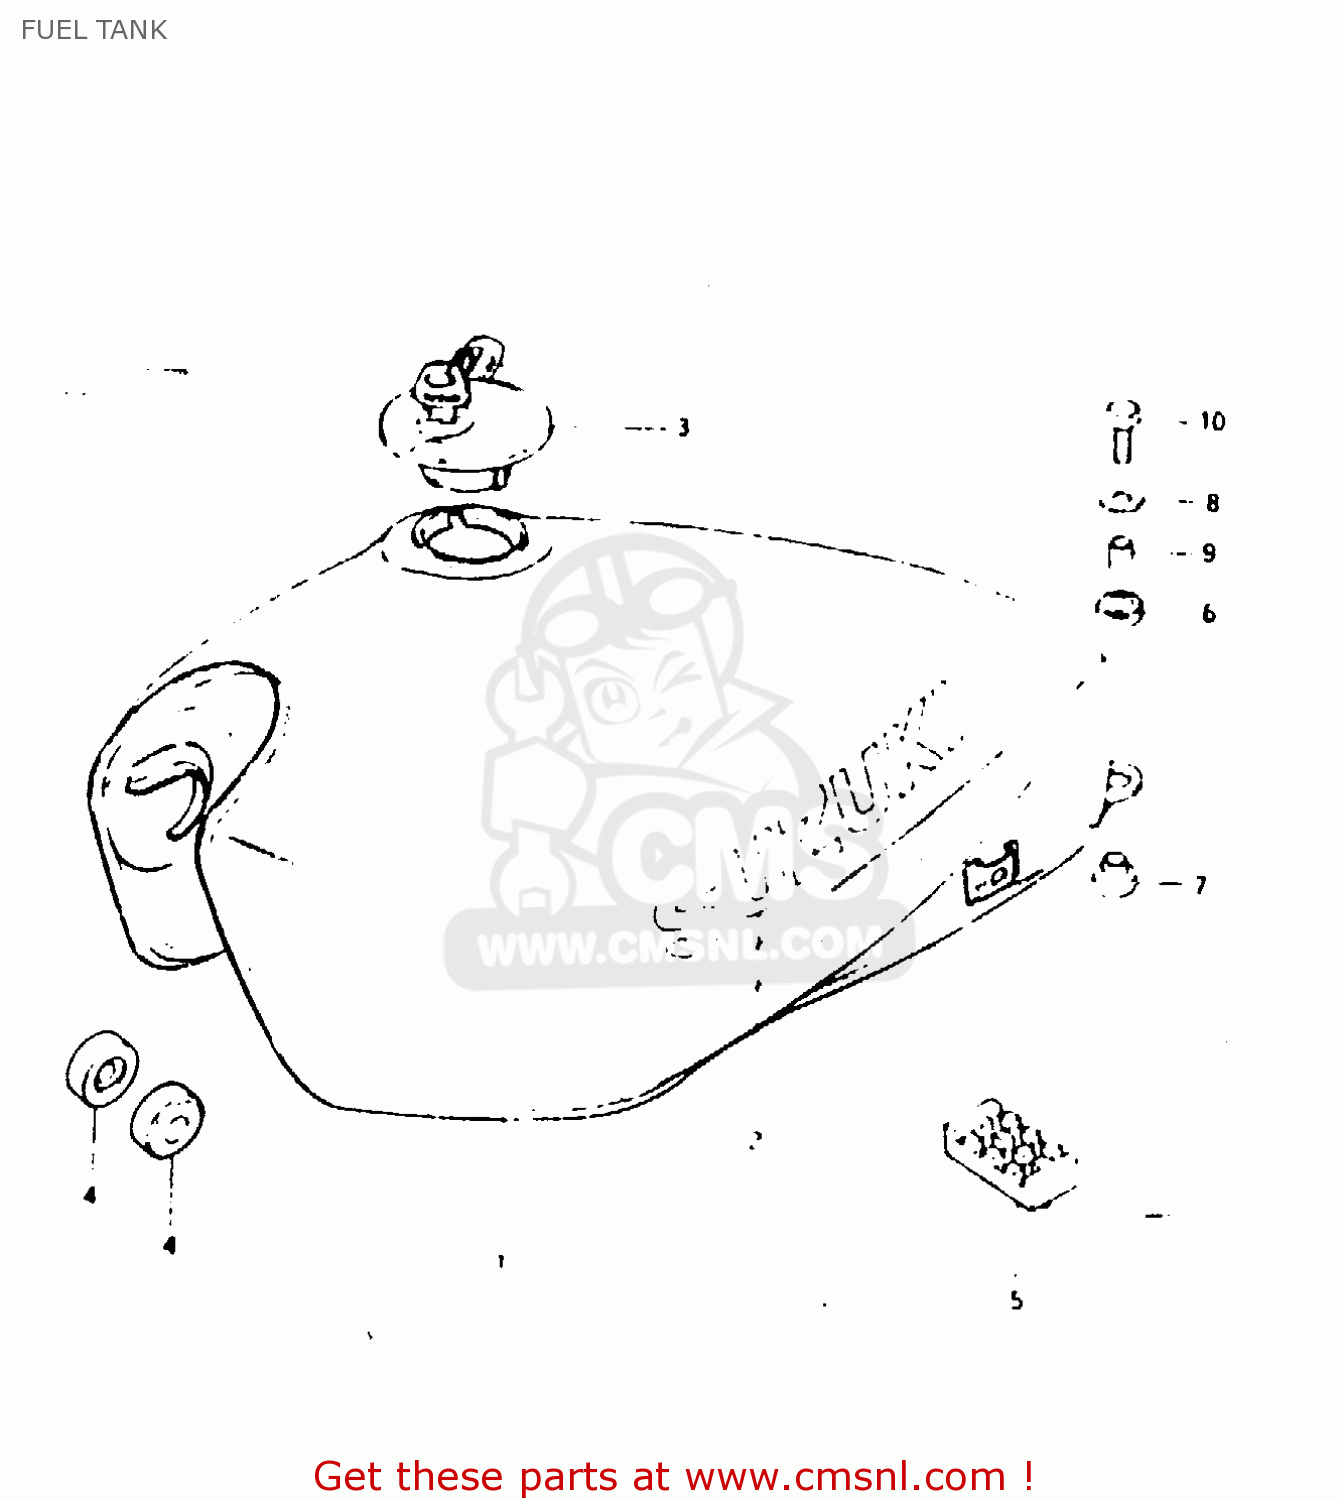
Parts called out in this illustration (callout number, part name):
1	TANK, FUEL (SILVER)
2	EMBLEM(ORANGE)
3	CAP SET,FUEL TANK
4	CUSHION
5	CUSHION,FUEL TANK CTR
6	CUSHION
7	CUSHION
8	WASHER (6.5X24X1.6)
9	SPACER
10	BOLT
